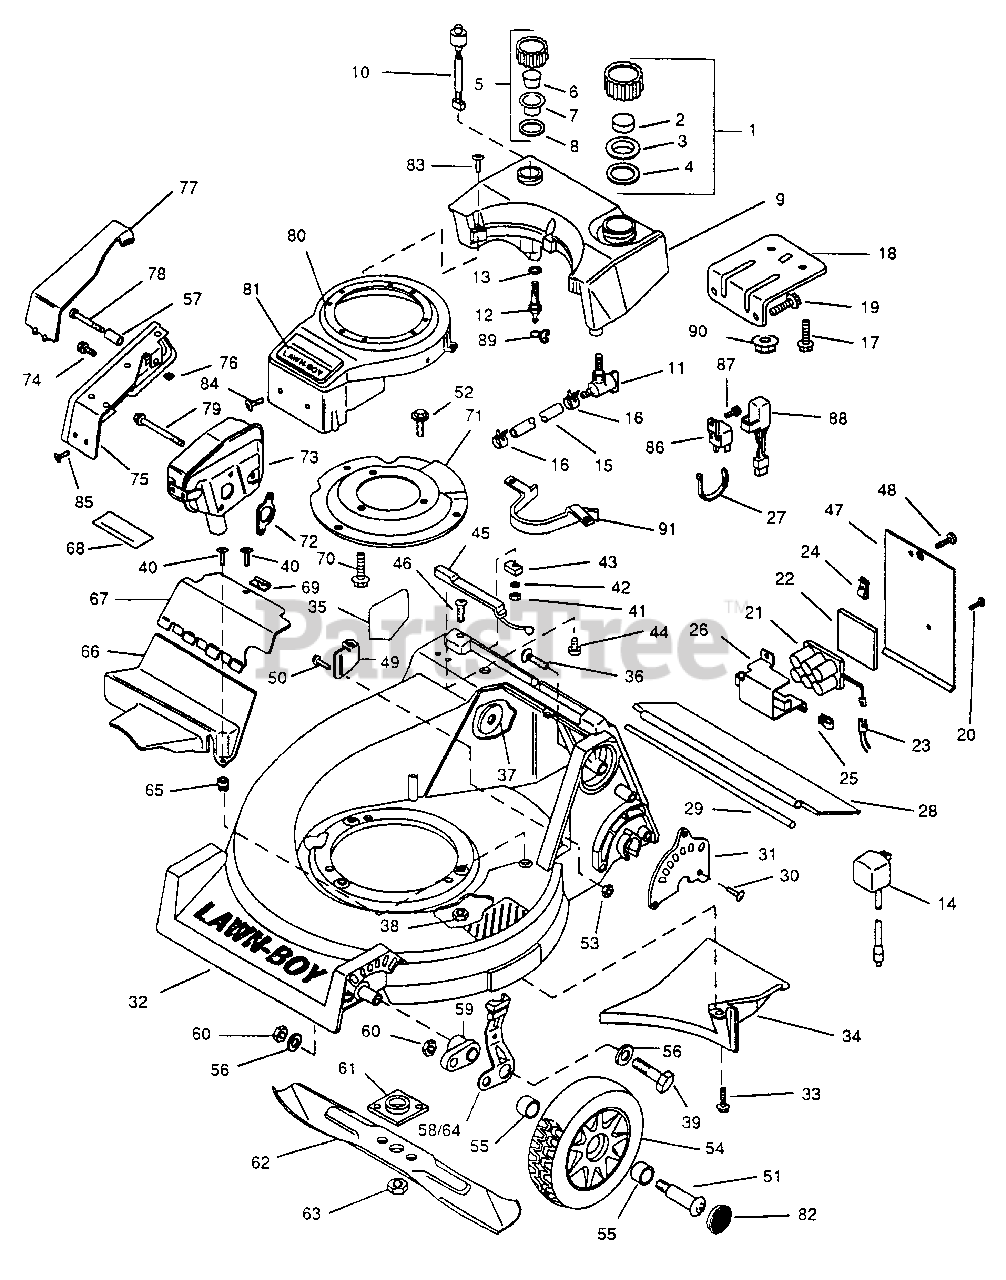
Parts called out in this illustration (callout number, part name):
1	Fuel Cap Assembly (Inc. 2-4)
2	Baffle
3	Baffle Cover
4	Gasket
5	Oil Cap Assembly (Inc. 6-8)
6	Baffle
7	Baffle Cover
8	Gasket
9	Fuel/Oil Tank Assy (Inc. 10-13)
10	Switch-Low Oil
11	Fuel Shut-Off Valve
12	Oil Fitting Assembly (Inc. 13)
13	O-Ring
14	Battery Charger (680564)
15	Fuel Line
16	Clamp-Fuel Line
17	Screw-Fuel Tank Mounting
18	Fuel Tank Bracket (680564)
19	Bolt-Bracket & Starter (680564)
20	Screw-Battery Bracket (680564)
21	Battery Pack (680564)(Inc. 22)
22	Pad-Battery (680564)
23	Wire Harness, Lower (680564)
24	Speednut
25	Speednut (680564)
26	Battery Bracket (680564)
27	Tie Strap (680564)
28	Trailing Shield
29	Rod-Trailing Shield
30	Screw-Plate to Housing
31	Height Adjust Plate
32	Housing Assy (Inc. 33-37)
33	Screw-Baffle to Housing
34	Baffle
35	Decal-Blade Contact Warning
36	Handle Mounting Bolt
37	Washer-R.H. Handle Mounting
38	Locknut-Mtg Plate To Housing
39	Screw
40	Screw
41	Nut
42	Lockwasher
43	Magnet Assembly
44	Screw
45	Switch-Bag Lock
46	Screw
47	Access Door
48	Screw
49	Cable Anchor
50	Bolt
51	Shoulder Bolt-Wheel
52	Screw-Mtg Plate To Housing
53	Nut-Cable Anchor To Housing
54	Wheel & Tire Assy (Inc. 55)
55	Bushing
56	Washer
57	Spacer-Muffler Guard
58	Knob & Spring Assembly-L.H.
59	Front Height Adj Arm
60	Nut
61	Collar & Plate Assembly
62	21" Blade
63	Nut-Blade
65	Grommet
66	Lower Drive Cover
67	Upper Drive Cvr w/Decal (Inc. 68)
68	Decal-Warning
69	Speednut
70	Screw-Mtg. Plate To Engine
71	Engine Mounting Plate
72	Exhaust Gasket
73	Muffler
74	Screw-Muffler Guard
75	Muffler Guard Assy (Inc. 76-77)
76	Pushnut
77	Muffler Cover
78	Screw-Muffler Guard
79	Screw-Muffler
80	Shroud & Applique Assy (Inc. 81)
81	Applique
82	Cap-Hub
83	Screw-Fuel Tank
84	Screw-Shroud
85	Screw-Muffler Guard
86	Starter Relay (680564)
87	Screw-Relay (680564)
88	Electronic Cup Assy (680564)
89	Clamp-Oil Hose
90	Nut (680562)
91	Belt Snubber
